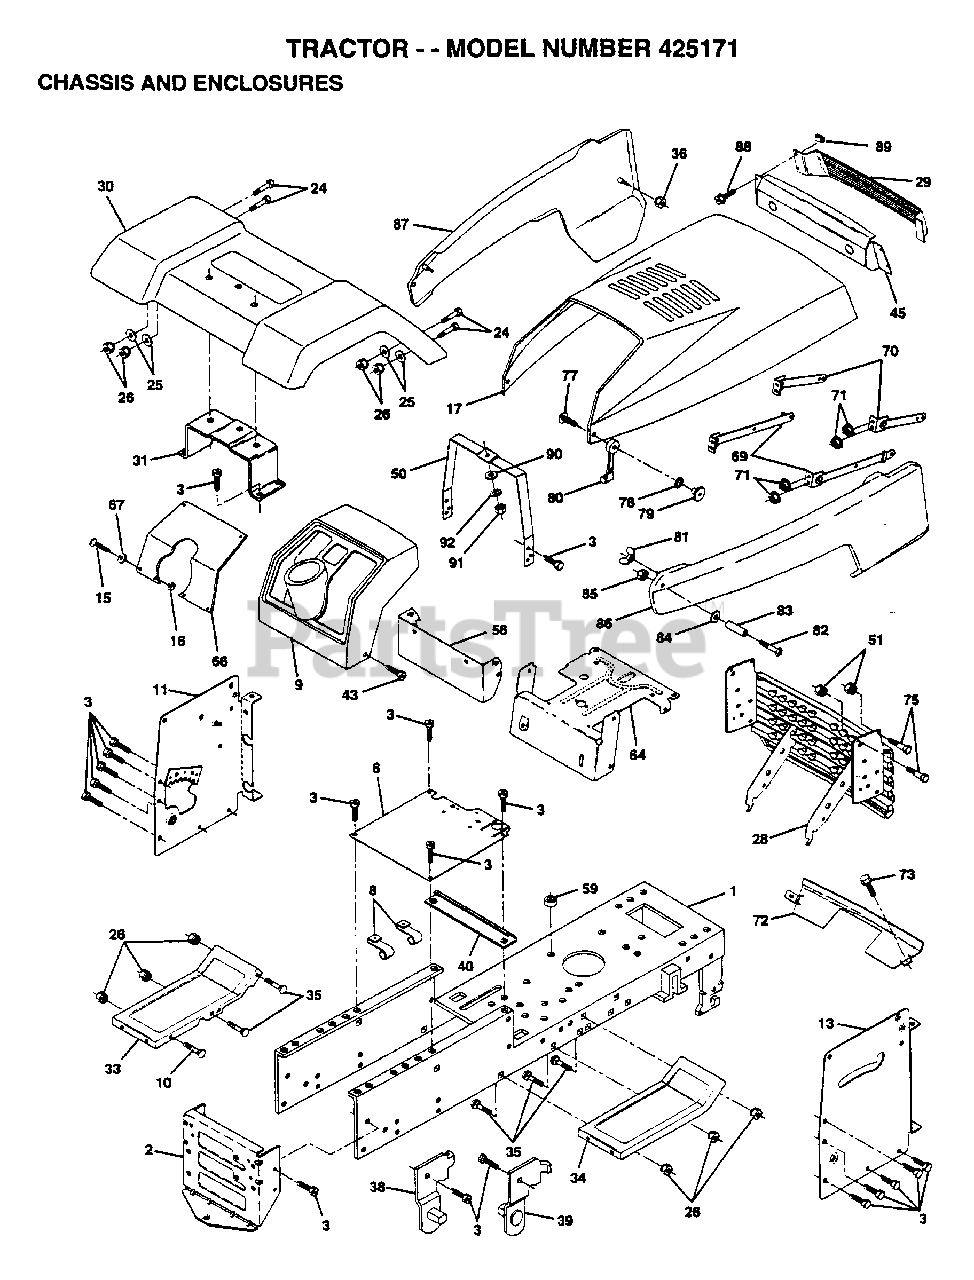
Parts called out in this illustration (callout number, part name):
1	CHASSIS.WLD.11GA
3	SCREW
8	"CLIP,INSULATOR"
9	DASHBOARD BLACK
11	PANEL.DASH.LH
13	PANEL.DASH.RH.
24	BOLT
25	WASHER
26	NUT
29	LENS LT
31	BRACKET SUPT FEND
35	BOLT
36	PAL NUT LT
38	BRACKET ASM LH
39	BRACKET ASM RH
40	SPACER FENDER LT
41	PLATE EXTEN FEND
43	WASHER
50	DASH.SUPT.YP/HUSQ
51	NUT
56	BOLT
67	WASHER
71	NUT HXKEP 1/4X20
73	SCREW CRT
77	SCREW
78	LOCKWASHER
79	WELDNUT
80	HOOD LATCH T
81	WINGNUT.1/20.NYL.
82	SCREW
83	SPACER LT
84	WASHER
89	"""J"" FASTENER LT"
90	WASHER PM
92	LOCKWASHER
129	WASHER
